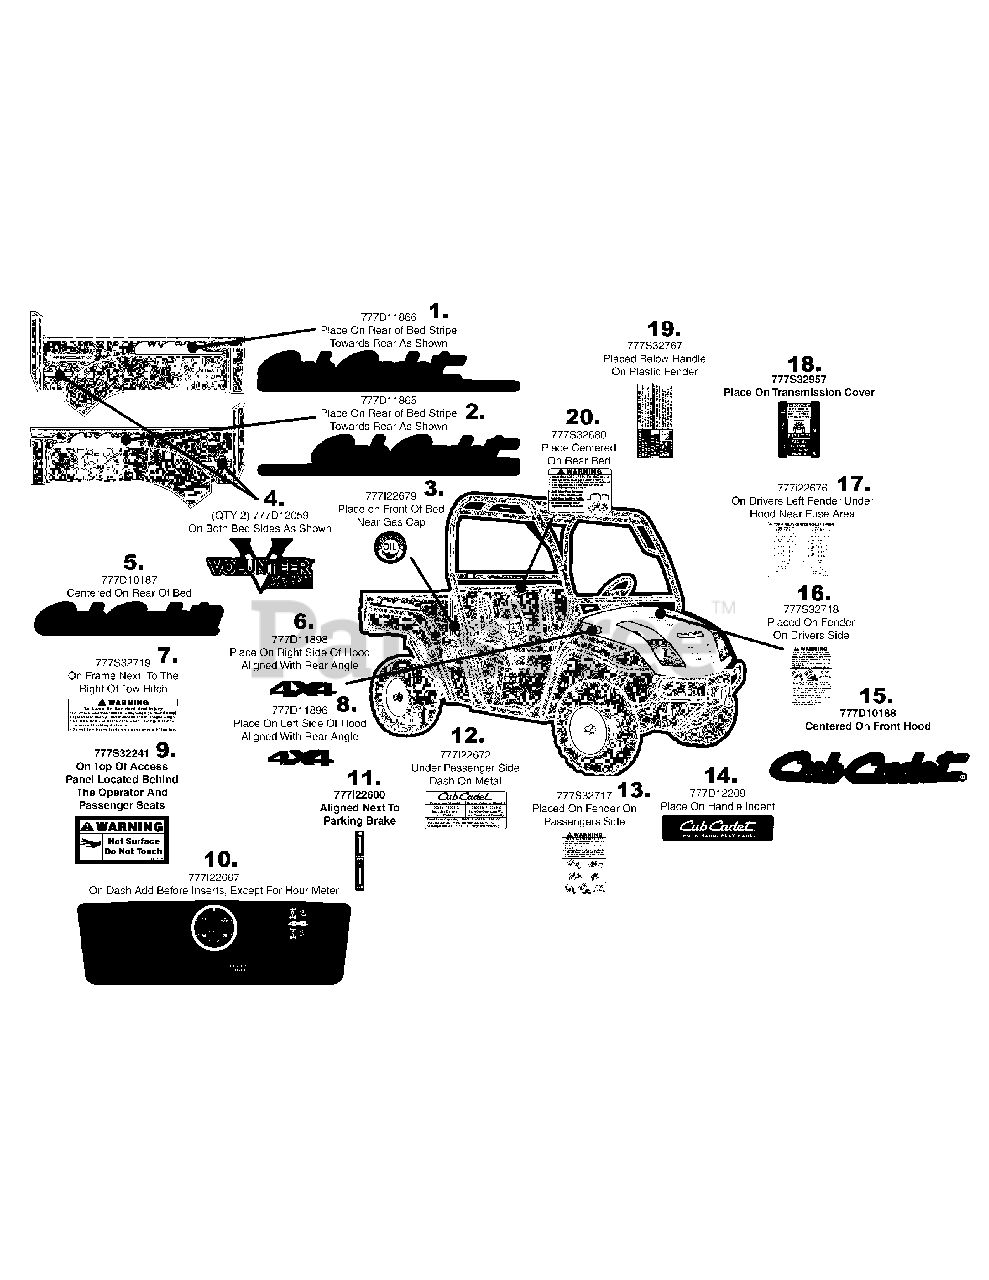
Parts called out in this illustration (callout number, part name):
1	LABEL-UV CUB CAMO EURO LEFT
2	LABEL-UV CUB CAMO EURO RIGHT
3	LABEL-CHECK ENG OIL
4	LABEL-UV VOL CAMO 624
5	LABEL-SNW:CUB LOGO BLK BG
6	LABEL-CUB UV 4X4 HOOD RH CAMO
7	LABEL-TOW HITCH
8	LABEL-CUB UV 4X4 HOOD LH CAMO
9	LABEL-HOT SURFACE
10	LABEL-DASH
11	LABEL-PARK BRAKE
12	LABEL-OPERATING WGT AIR COOL
13	LABEL-RIDER FALL RH FENDER
14	LABEL-UV DASH LOGO CAMO
15	LABEL-CUB CADET HOOD
16	LABEL-ROLL & FALL LH FENDER
17	LABEL:UV:4X4 KOHLER FUSE
18	LABEL:CUB:BENCH SEAT WARN
19	LABEL-4X4 CARGO BOX HANDLE
20	LABEL-CARGO LOAD
